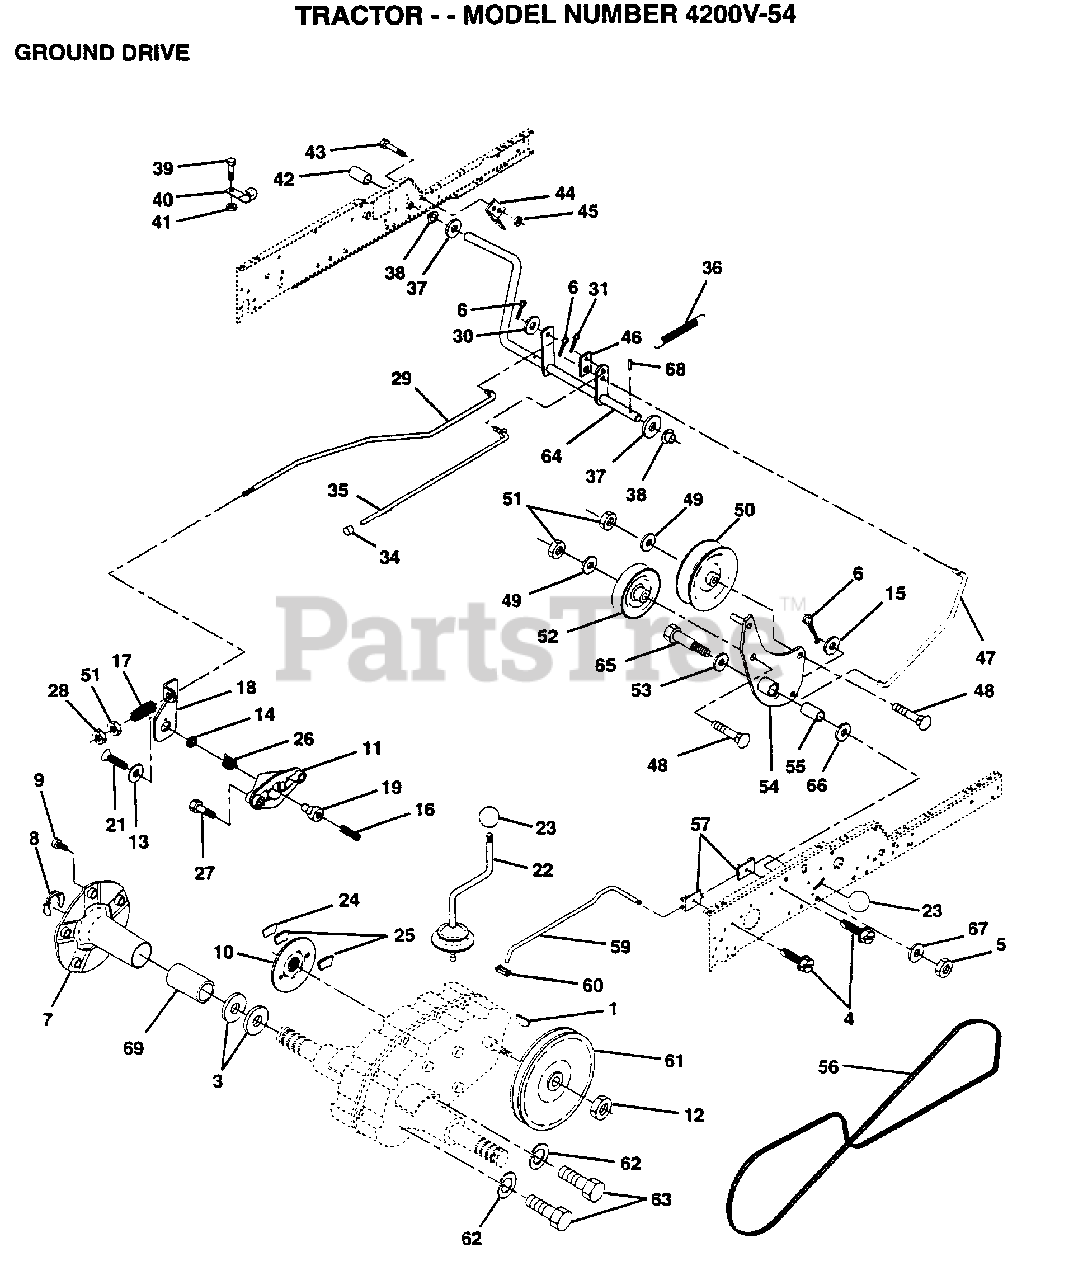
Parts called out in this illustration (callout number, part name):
3	WASHER T
4	SCREW LT
6	COTTER PIN
8	KLIP RING
9	BOLT.HUB.WHL.REAR
10	BRAKE.DISC.
11	YOKE BRAKE DISC
12	NUT STD
13	WASHER SPECIAL
14	BUSHING LEVER BKT
15	WASHER
16	SCREW SET 1/4-20
17	"SPRING,ROD BRAKE"
18	LEVER BRAKE GT
19	CAM BRAKE DISC GT
21	SCREW FLT 1/4X28
22	GEAR SHFT LVR T
23	KNOB
24	SUPPORT PUCK BRKE
25	PUCK BRAKE TOP
26	SPRING RET BRAKE
27	SCREW HX WASH
28	NUT
29	ROD BRAKE ZINC GT
30	WASHER
34	PLUNGER CAP T
35	ROD BRAKE PART GT
37	WASHER
38	NYLINER T
39	SCREW
40	ACT-SWITCH T
42	PEDAL COVER T
43	SCREW
44	BRKT SWITCH GT
45	"NUT,KEPS"
46	RETAINER SPRING
47	ROD.CLUTCH
48	BOLT
49	WASHER
50	FLAT IDLER PULLEY
52	PULLEY.IDLER.V.GR
53	WASHER T
54	ARM.ASM.IDLER.CLU
55	"LY, BEARING"
56	BELTV.GR.DR.83.
57	BRACKET.ROD.SHIFT
59	ROD SHIFT HI LO
60	CONNECTING LINK
62	LOCKWASHER
63	BOLT
65	AXLE BOLT
66	WASHER.HARD.BLADE
67	WASHER
68	ROLL PIN STD
69	"COVER, HUB"
